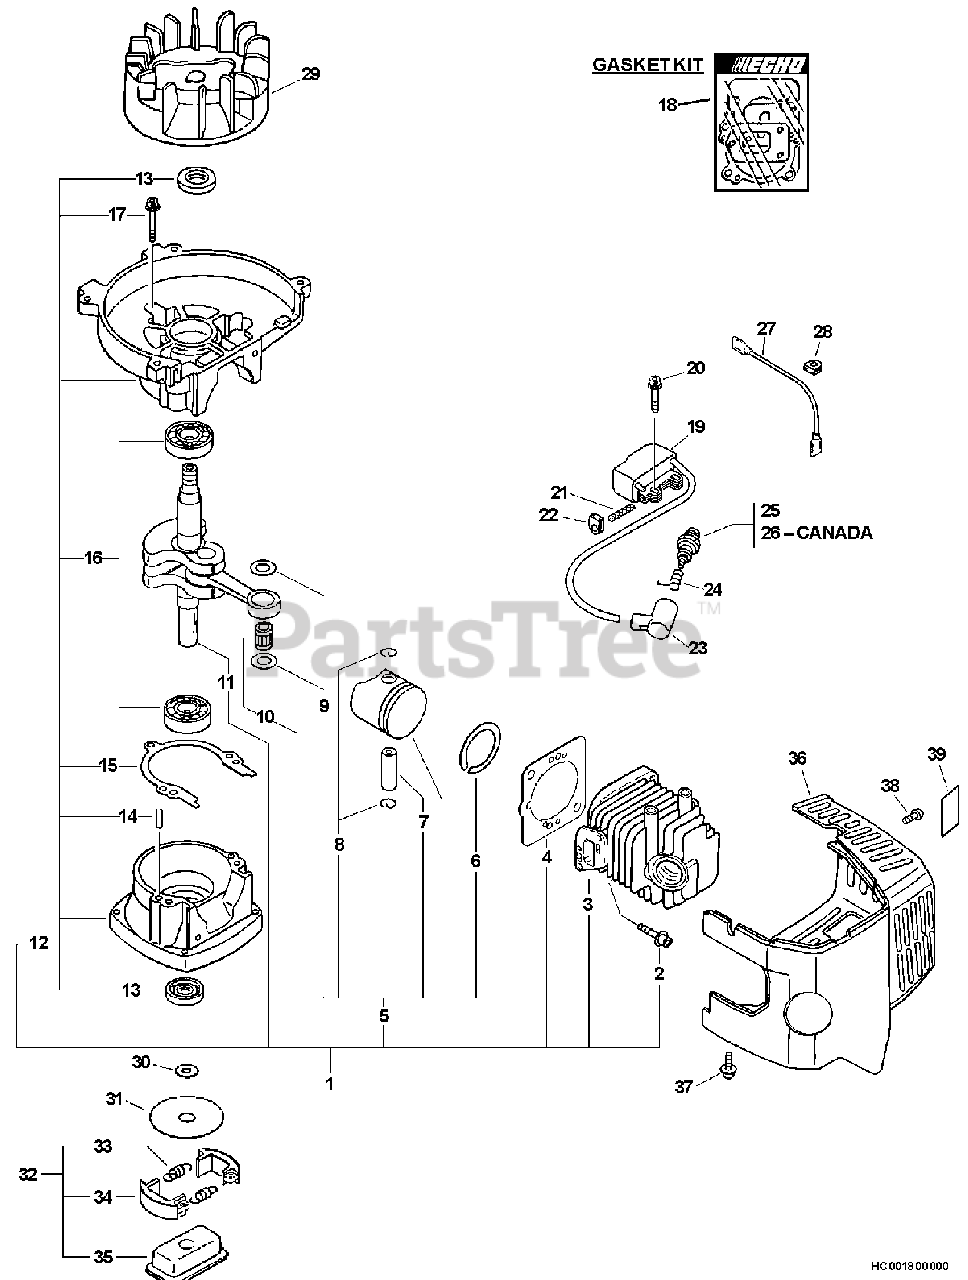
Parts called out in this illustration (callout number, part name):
1	SHORT BLOCK
2	BOLT 5×22
3	CYLINDER
4	GASKET, CYLINDER
5	PISTON KIT
6	RING, PISTON
7	PIN, PISTON 8
8	RING, SNAP
9	WASHER, THRUST
10	BEARING, NEEDLE
11	CRANKSHAFT ASSY
12	CRANKCASE KIT
13	SEAL, OIL 12
14	PIN, LOCATING 4
15	GASKET, CRANKCASE
16	BEARING, BALL - 6201 C3
17	BOLT 5×28
18	GASKET KIT
19	COIL, IGNITION
20	BOLT 4×20
21	TUBE, INSULATOR
23	CAP, SPARK PLUG
24	TERMINAL, SPARK PLUG
25	SPARK PLUG - BPM8Y
26	SPARK PLUG - BPMR8Y
27	LEAD
29	FLYWHEEL
30	WASHER, CLUTCH
31	PLATE, CLUTCH
32	CLUTCH ASSY
33	SPRING, CLUTCH
34	SHOE, CLUTCH
35	BOSS, CLUTCH
36	COVER, ENGINE
37	BOLT 4×20
38	BOLT 4×8
39	LABEL, CAUTION - HOT
